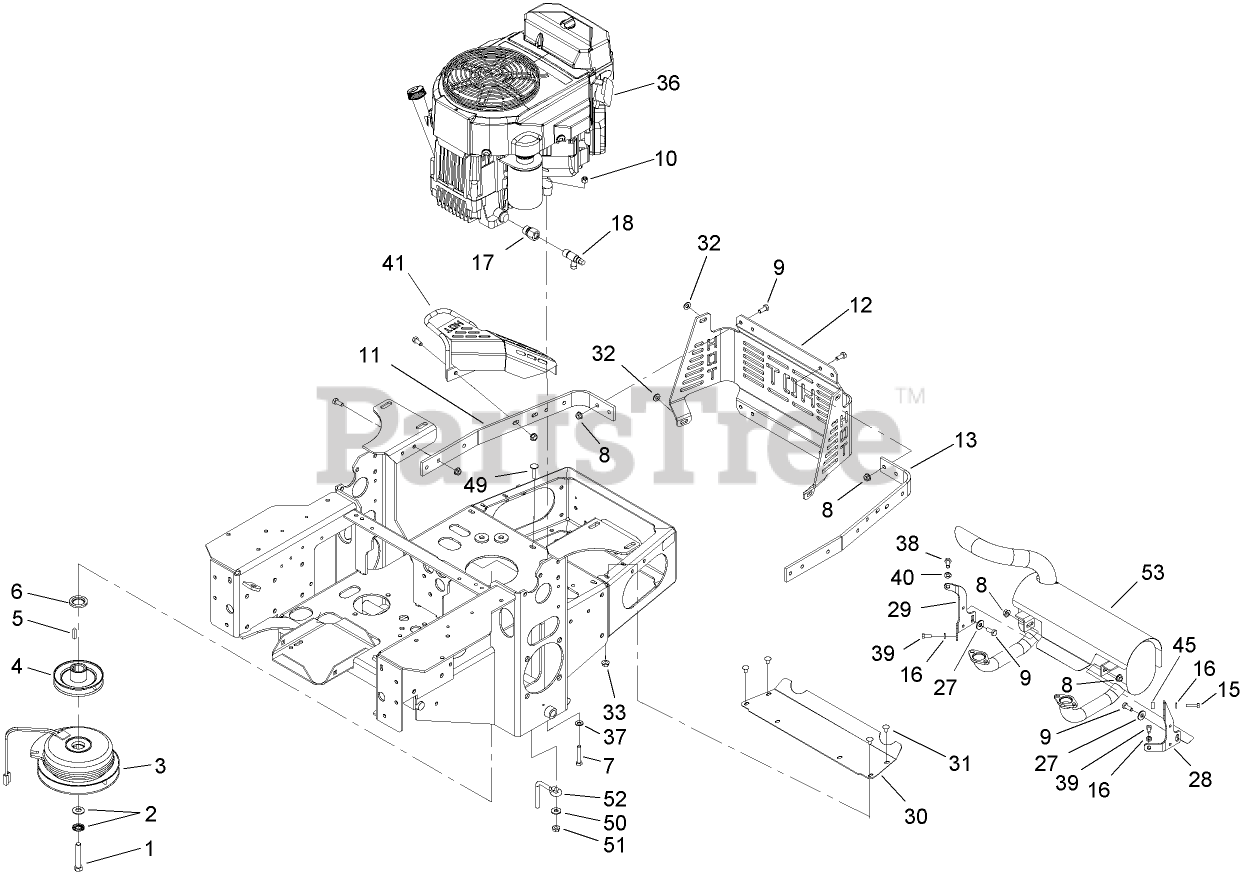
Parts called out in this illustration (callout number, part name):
1	SCREW-HH
2	WASHER-SPRING
3	CLUTCH
4	PULLEY
6	Spacer-Crankshaft
7	SCREW-HH
8	NUT-HF
9	SCREW-HH
10	NUT-LOCK, NI
11	STRAP-GUARD, RH
12	GUARD-REAR
13	STRAP-GUARD, LH
15	SCREW-HH
16	WASHER-LOCK
17	Adapter
18	Valve-Drain, Oil
27	WASHER-FLAT
28	Bracket-Muffler, LH
29	Bracket-Muffler, RH
30	Deflector-Short
31	SCREW-CARR
32	WASHER-PLAIN
33	NUT-HF
37	WASHER-SPRING
38	SCREW-HH
39	SCREW-HH
40	WASHER-LOCK
41	GUARD-TAILPIPE
45	Spacer
49	SCREW-CARR
50	WASHER-FLAT
51	NUT-HF
52	ROD-BELT
53	MUFFLER KIT
